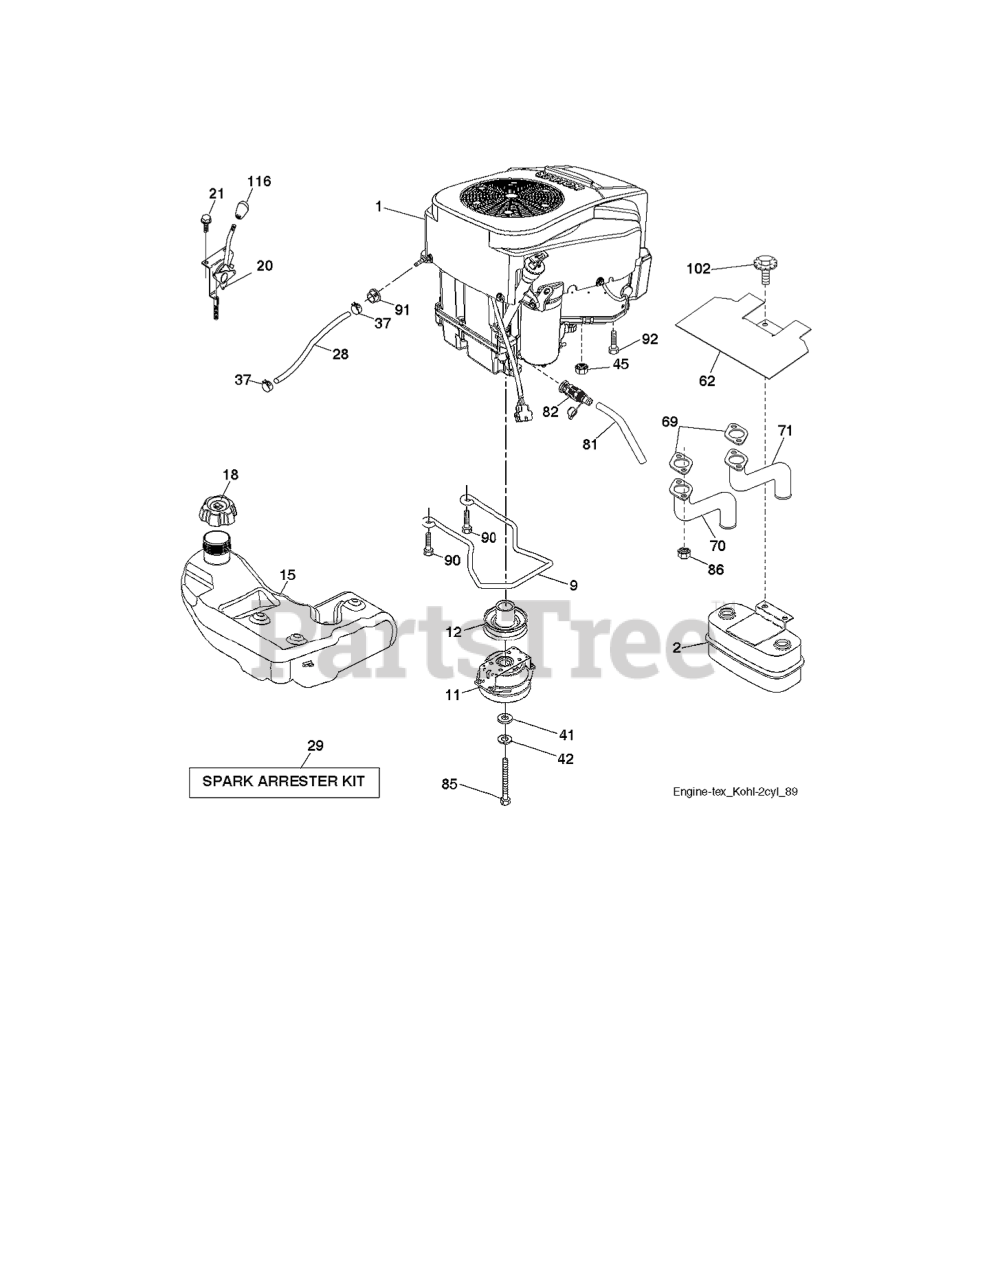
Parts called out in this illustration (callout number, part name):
2	MUFFLER.ASM.TWIN.MNTG.BRACKET
11	CLUTCH.OGURA.5.0PD.GT1.5A-EH07
12	PULLEY.ENGINE.TUFFTORQ
15	FUEL TANKS
18	FUEL CAP
18	CAP ASSY FUEL 3" GRAY
20	THROTTLE.KOHL.PRO.#88PAD_46"
21	SCREW.#10X.750
28	LINE.FUEL.64"REAR.EMIS
29	KIT.SPARK ARRESTOR 794945 B&S
37	HOSE CLAMP
62	SHIELD.HEAT.MUFFLER
69	GASKET.EXHAUST.KOHL.CV18-CV26
70	PIPE.EXHAUST.RH.CV18/20
71	PIPE.EXHAUST.LH.CV18/20
81	TUBE, DRAIN OIL ASM.
82	VALUE.OIL.DRAIN
85	BOLT.HEX.7/16-20X3.75.GR5.RED
86	NUT.HEX.FLANGE.TOPLOCK
90	SCREW 3/8-16X1
91	BUSHING.1.375OD
92	SCREW.3/8-16
102	SCREW
116	KNOB - SHIFT
